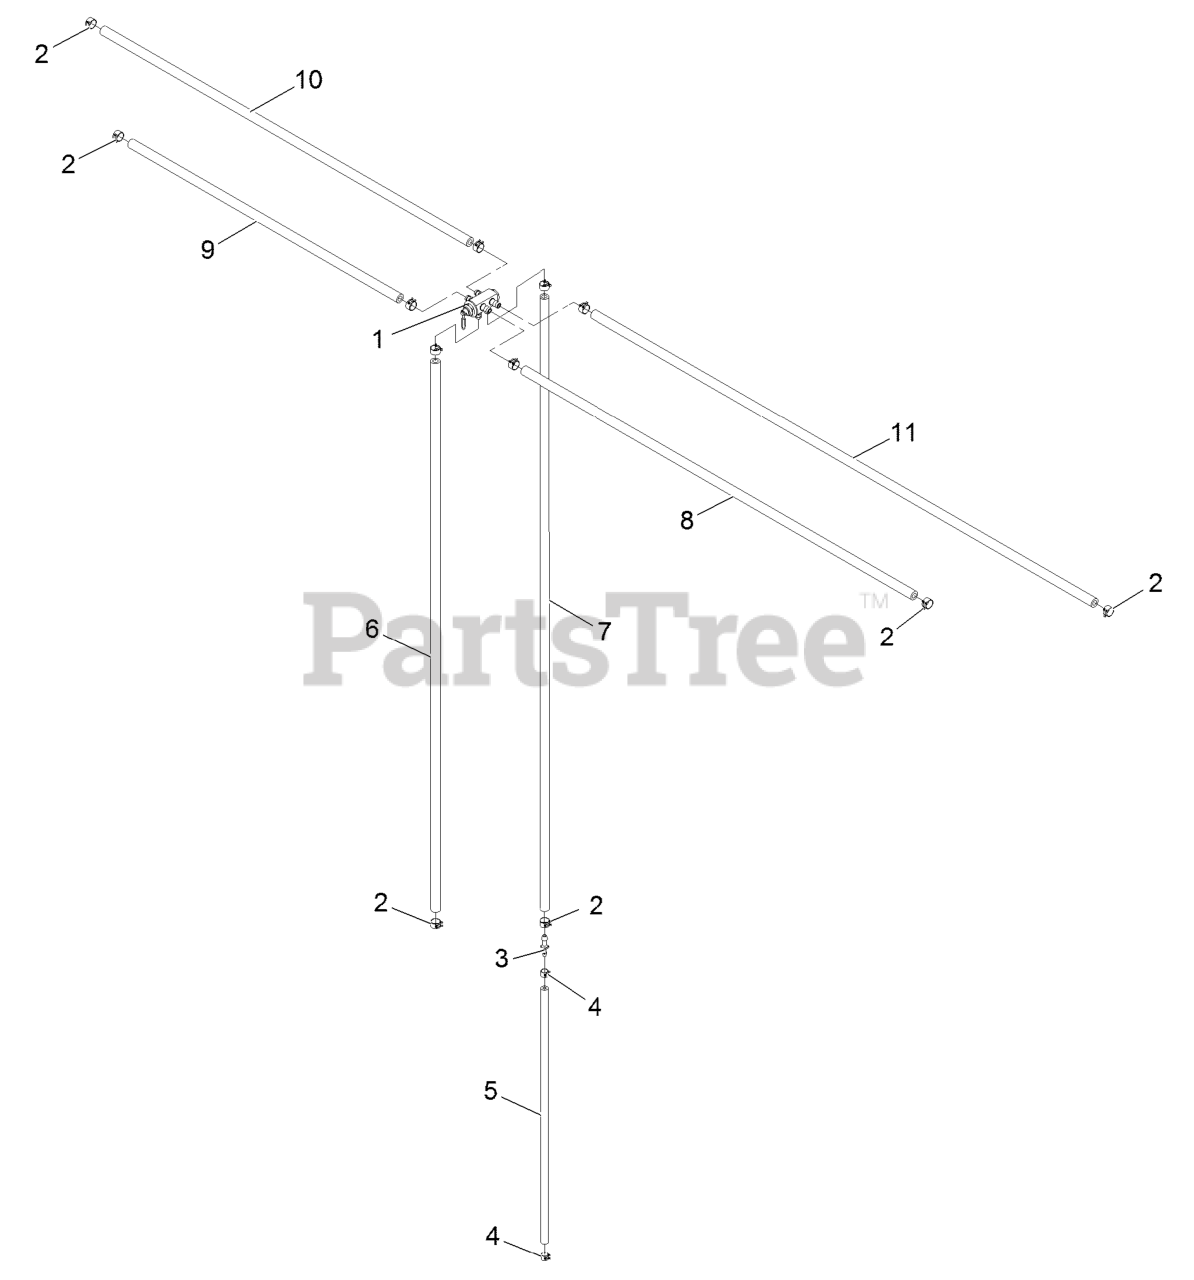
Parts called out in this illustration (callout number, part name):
1	VALVE,FUEL SELECTOR 5/16
2	CLAMP-HOSE
3	FITTING-STRAIGHT
4	CLAMP-HOSE
5	HOSE-FUEL
6	HOSE-FUEL
7	HOSE-FUEL
8	HOSE-FUEL
9	HOSE-FUEL
10	HOSE-FUEL
11	HOSE-FUEL
